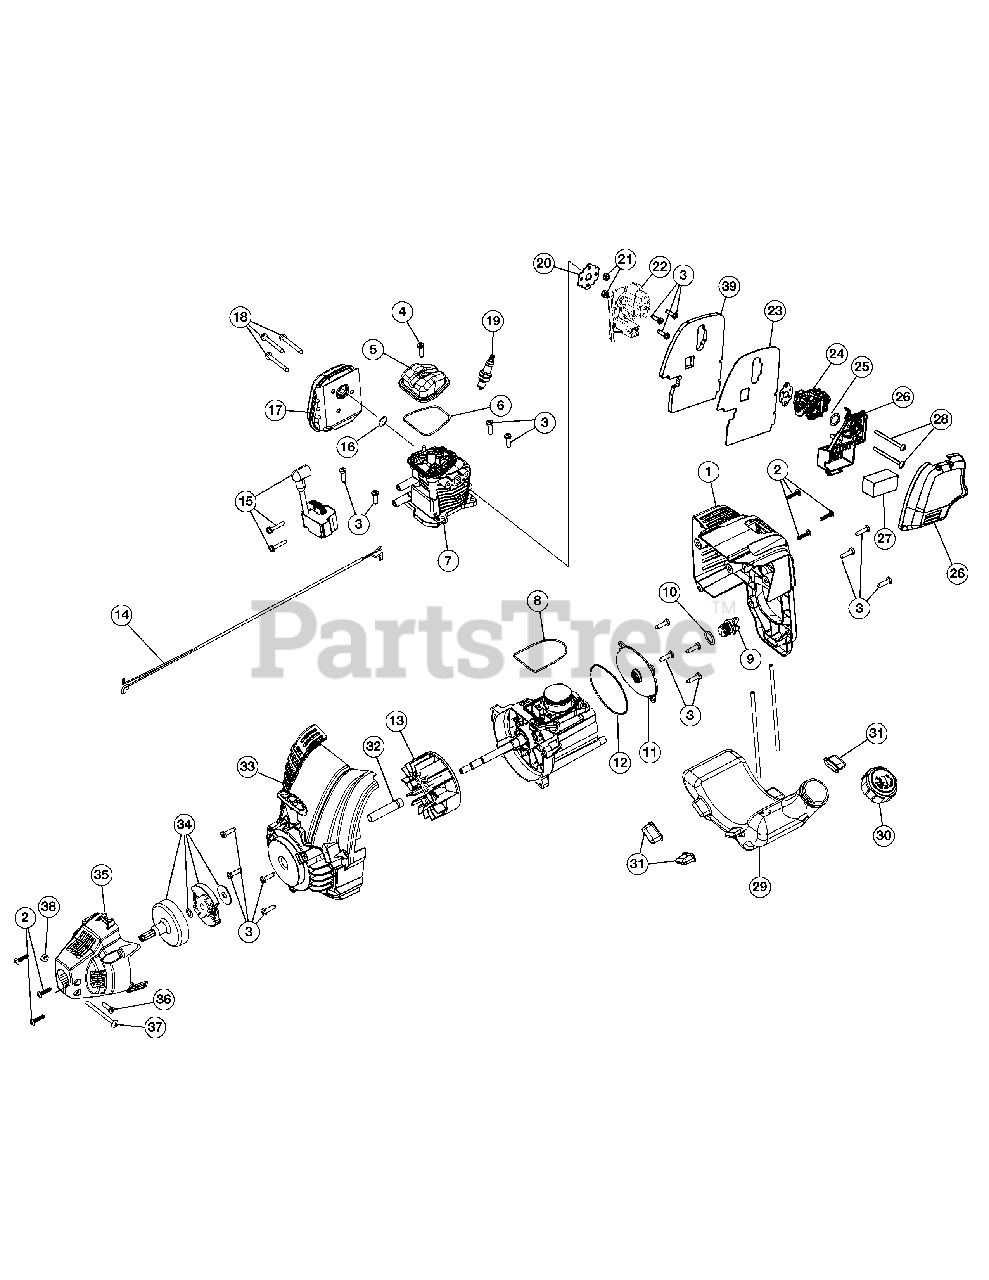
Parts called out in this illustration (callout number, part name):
1	Engine Cover Assembly (Incl. 2 & 3)
2	Cover Screw
3	Housing Screw
4	Rocker Cover Screw
5	Rocker Cover
6	Rocker Cover O-Ring
7	Cylinder Assembly (Incl. 3 - 6 & 8)
8	Cylinder O-Ring
9	Oil Plug (Incl. 10)
10	Oil Plug O-Ring
11	Crankcase Cover
12	Crankcase Cover O-Ring
13	Flywheel Assembly
14	Lead Wires
15	Module Assembly
16	Muffler Gasket
17	Muffler Assembly (Incl. 16 & 18)
18	Muffler Screw
19	Spark Plug
20	Insulator Gasket
23	Carburetor Gasket
24	Carburetor
26	Air Cleaner Cover Assembly (Incl. 27)
27	Air Filter
29	Fuel Tank Assembly w/Fuel Lines (Incl. 30)
31	Fuel Tank Pads
33	Starter Housing Assembly (Incl. 3)
34	Clutch Assembly
35	Clutch Cover (Incl. 2)
36	Anti-Rotation Screw
37	Clamp Screw
39	Heatshield Carb.
